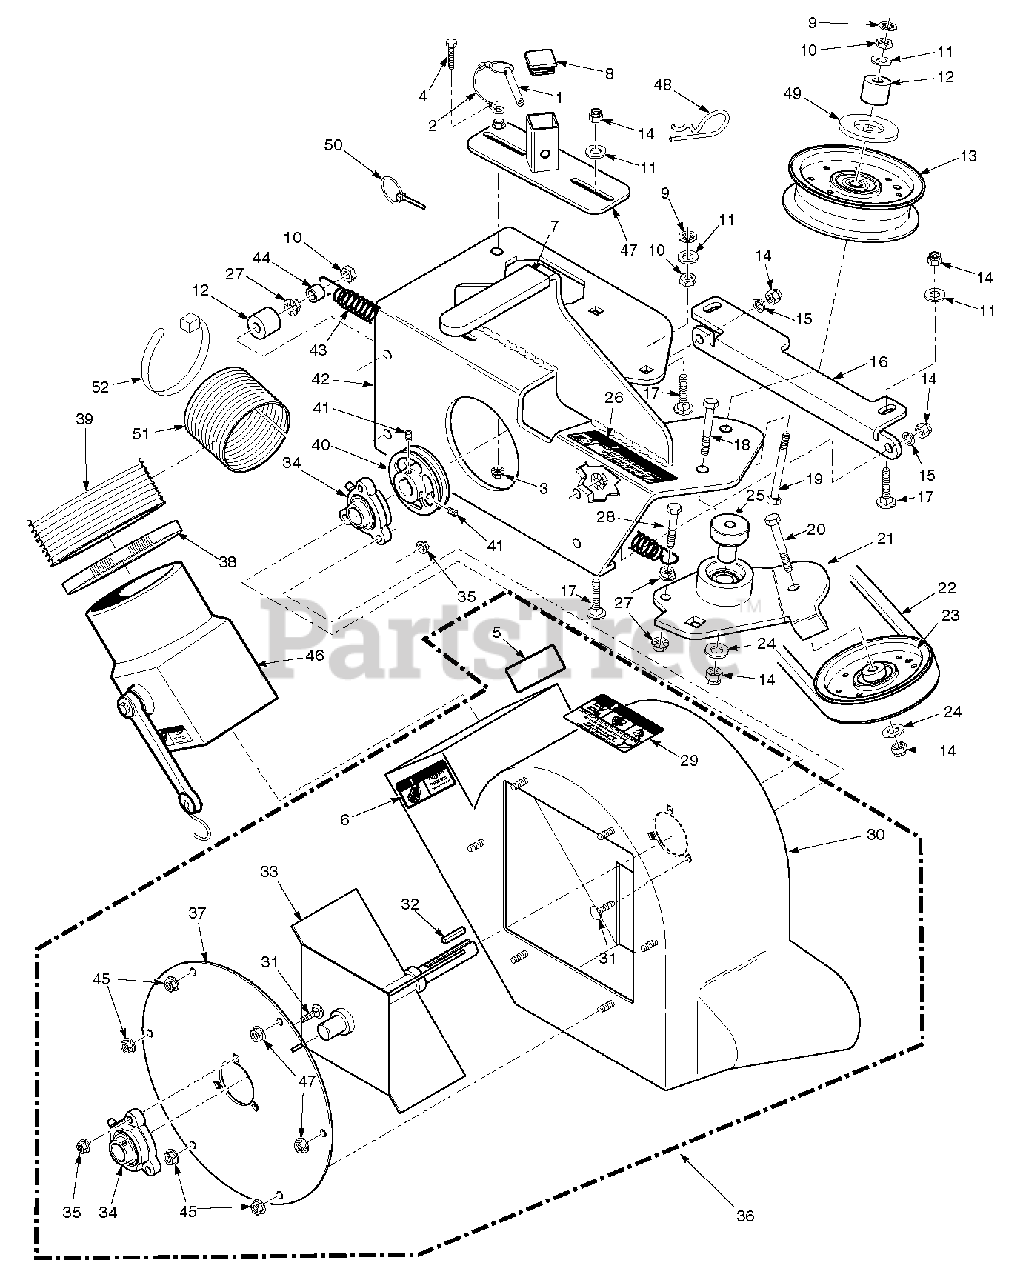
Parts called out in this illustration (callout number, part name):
1	Pin, Ring 2-1/4" Long
2	Lanyard, Deck Height Pin
3	Nut, Serr. Flange 1/4-20
4	Bolt, Hex Head 1/4-20 x 1-1/4"
5	Decal, Blower
6	Decal, Rotating Blower
7	Grip, Blower Lever
8	Cap, Square
9	Nut, Push On 3/8 Thread
10	Lock Nut, 3/8-16
11	Flatwasher, 3/8-.391 x .938 x .105
12	Spacer
13	Pulley, Idler 3-1/2" Dia.
14	Nut, Elastic Stop 3/8-16
15	Lockwasher, 3/8-16
16	Plate, Catcher Mounting
17	Bolt, Carr. 3/8-16 x 1-1/2"
18	Bolt, Hex Head 3/8-16 x 3" - 52"
19	Bolt, Hex Head 3/8-16 x 3-1/2"
20	Bolt, Hex Head 3/8-16 x 1-3/4"
21	Idler Arm Assembly
22	Belt, GC-SCZ-48V
22	Belt, GC-SCZ-52V
23	Pulley, 3-1/2" O.D., GC-STC
24	Washer, 3/8 Hardened
25	Pivot, Idler
26	Decal, Belt Cover
27	Nut, Serr. Flange 3/8-16
28	Bolt, Hex Head 3/8-16 x 1-1/2 Gr. 8
29	Decal, Danger
30	Blower Housing Weldment
31	Bolt, Carr. 5/16-18 x 3/4" Gr. 5
32	Key, 1/4 x 1/4 x 1-1/2"
33	Fan Weldment
34	Bearing Assembly
35	Nut, Elastic Stop 5/16-18
36	Blower Housing Assembly, GC-STT
37	Cover, Blower Housing
38	Clamp, 8-5/8" Max Dia.
39	Hose, 8.00" Dia. x 53" Long
40	Pulley, 4-3/4" O.D. - 1" Bore
41	Set Screw, 5/16-18 x 3/8"
42	Frame, Blower Mount
43	Spring, Main Drive
44	Spacer
45	Nut, Serr. Flange 5/16-18
46	Adapter w/Strap
47	Receiver Weldment, Mounting Post
48	Hair Pin Cotter, .177 x 3-1/4"
49	Dust Shield
50	Quick Pin, 5/16" Dia.
51	Hose, 8" Dia. x 24" Split
52	Cable Tie, .345 X 31.5 Black
